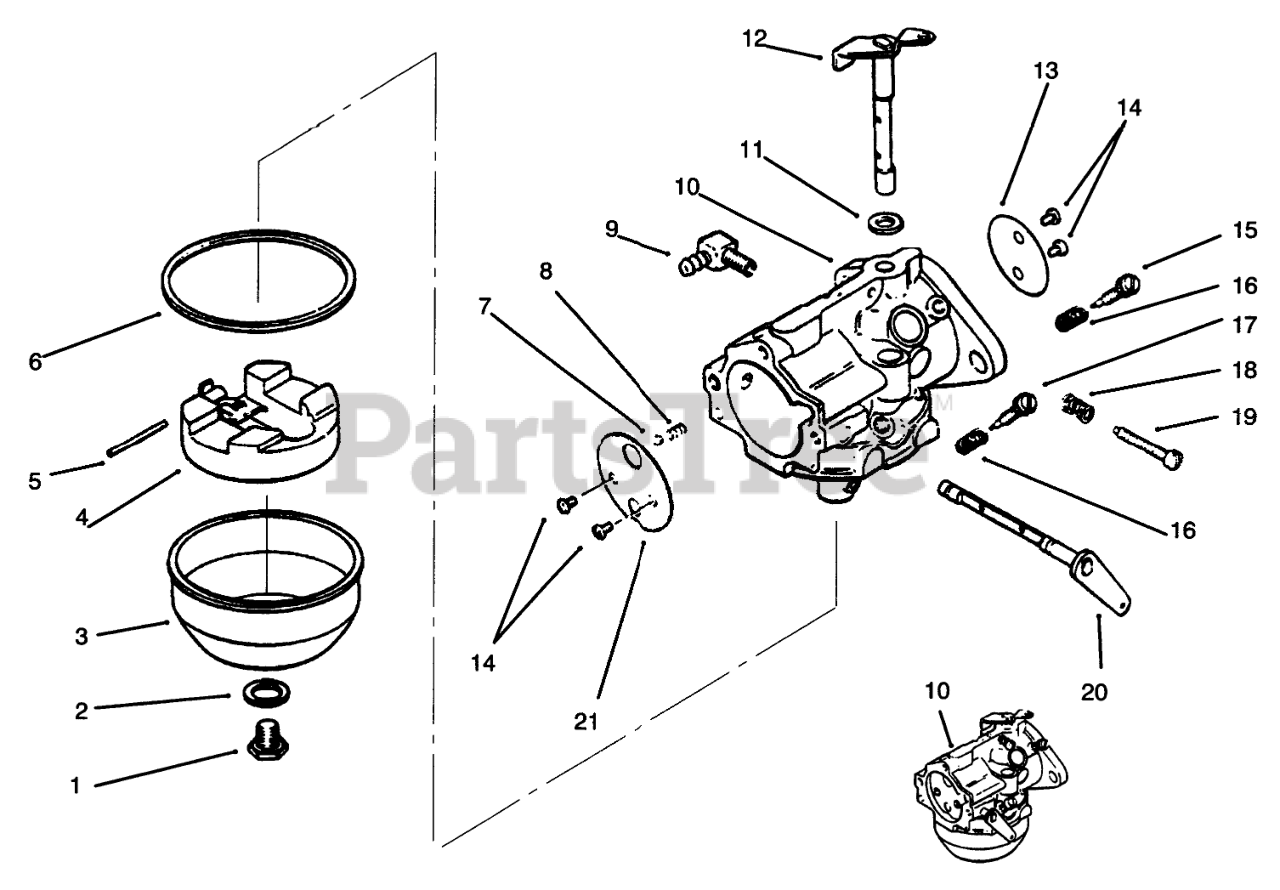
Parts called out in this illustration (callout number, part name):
1	Screw
2	Gasket
3	Bowl-Fuel
4	Kit-Float (Incl. Ref. #5)
5	Pin-Float
6	Gasket
8	Spring
10	Carburetor Assembly (Complete)
11	Seal ASM
12	Shaft w/Lever & Seal (Incl. Ref. #11)
13	Plate-Throttle
14	Screw
15	Idle Fuel Adj. Needle
16	Spacer
17	Main-Needle
18	Adj. Spring
19	Idle Speed Adj. Screw
20	Choke Shaft
21	Plate-Choke
